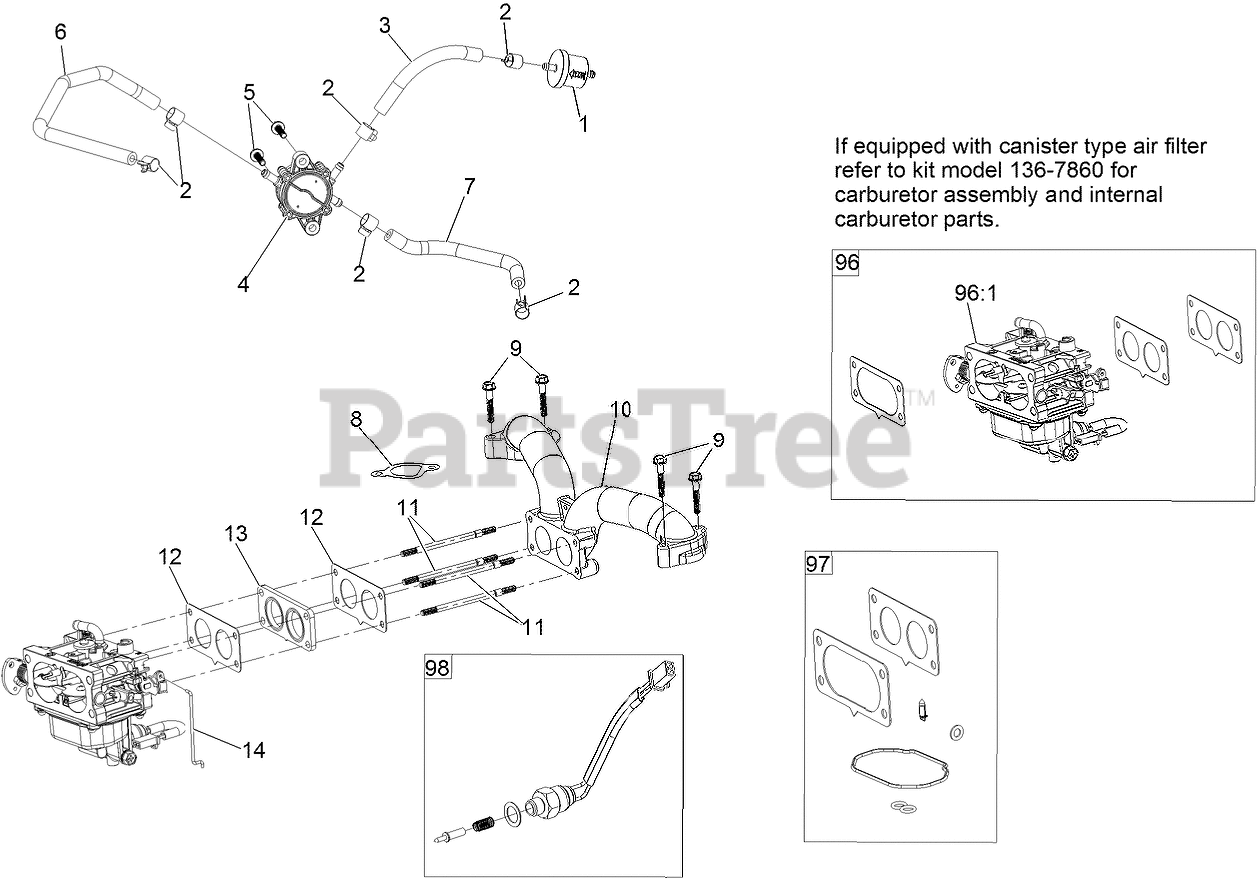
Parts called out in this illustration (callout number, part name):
1	FILTER-FUEL
2	CLAMP-FUEL LINE
3	LINE-FUEL
4	PUMP-FUEL
5	SCREW-HHF
6	HOSE-FUEL
7	HOSE-FUEL
8	GASKET-INTAKE
9	SCREW-HHF
10	MANIFOLD-INTAKE
12	GASKET-CARBURETOR
13	INSULATOR-CARBURETOR
14	LINKAGE-THROTTLE
96	CARBURETOR REPLACEMENT KIT
96:1	CARBURETOR
97	CARBURETOR REPAIR KIT
98	SOLENOID KIT
